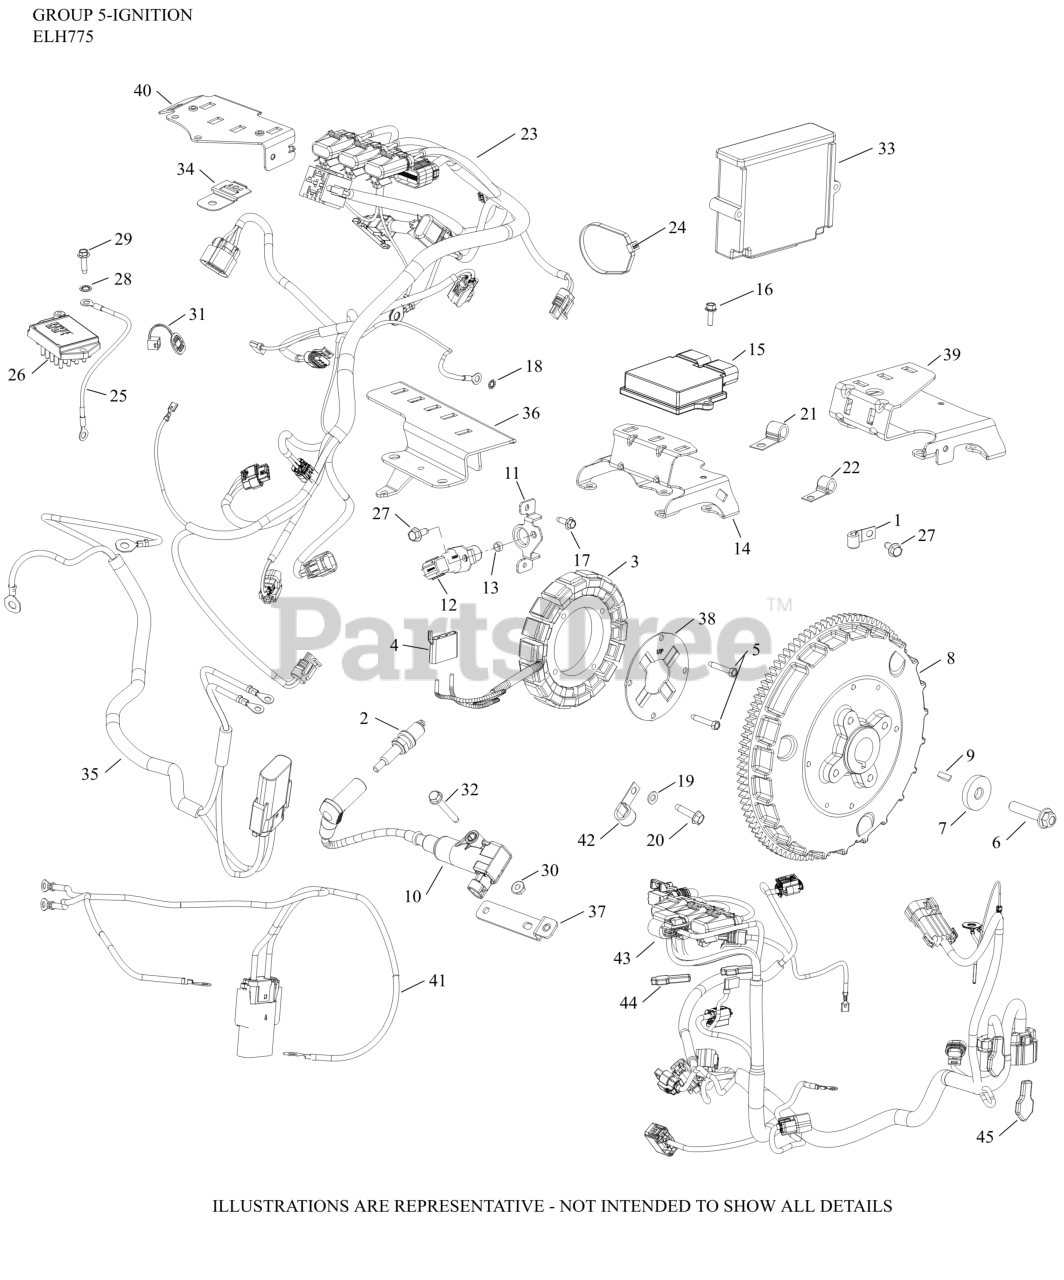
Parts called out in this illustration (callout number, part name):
2	SPARK PLUG
3	KIT, 25 AMP STATOR ASSY.
4	CONNECTOR
5	SCREW, THREAD FORMING
6	SCREW, FLG M10X1.5X45-USE 25 086 361-S
7	WASHER, FLAT 13/32"
8	FLYWHEEL, ASSEMBLY
9	KEY, 3/16" X 5/8"
10	COIL, IGNITION - EFI
11	BRACKET, SENSOR
12	SENSOR, SPEED
14	BRACKET, ECU, FUSE & CONNECTOR MOUNTING
15	MODULE, ECU
16	SCREW, HVY FLG M5X.8X16
17	SCREW, THREAD FORMING
18	WASHER, INT TOOTH LOCK #10
19	WASHER, FLAT 1/4" (O.D. 1/2")
20	SCREW, THREAD FORMING
22	CLIP, CABLE
23	HARNESS, WIRING (EFI, PHASE 1)
27	SCREW, THREAD FORMING
28	WASHER, INT TOOTH LOCK 1/4"
30	NUT, FLG M6X1.0
31	CAP, CONNECTOR
32	SCREW, THRD FRM M6X1.0X45
42	CLIP, CABLE (KM)
